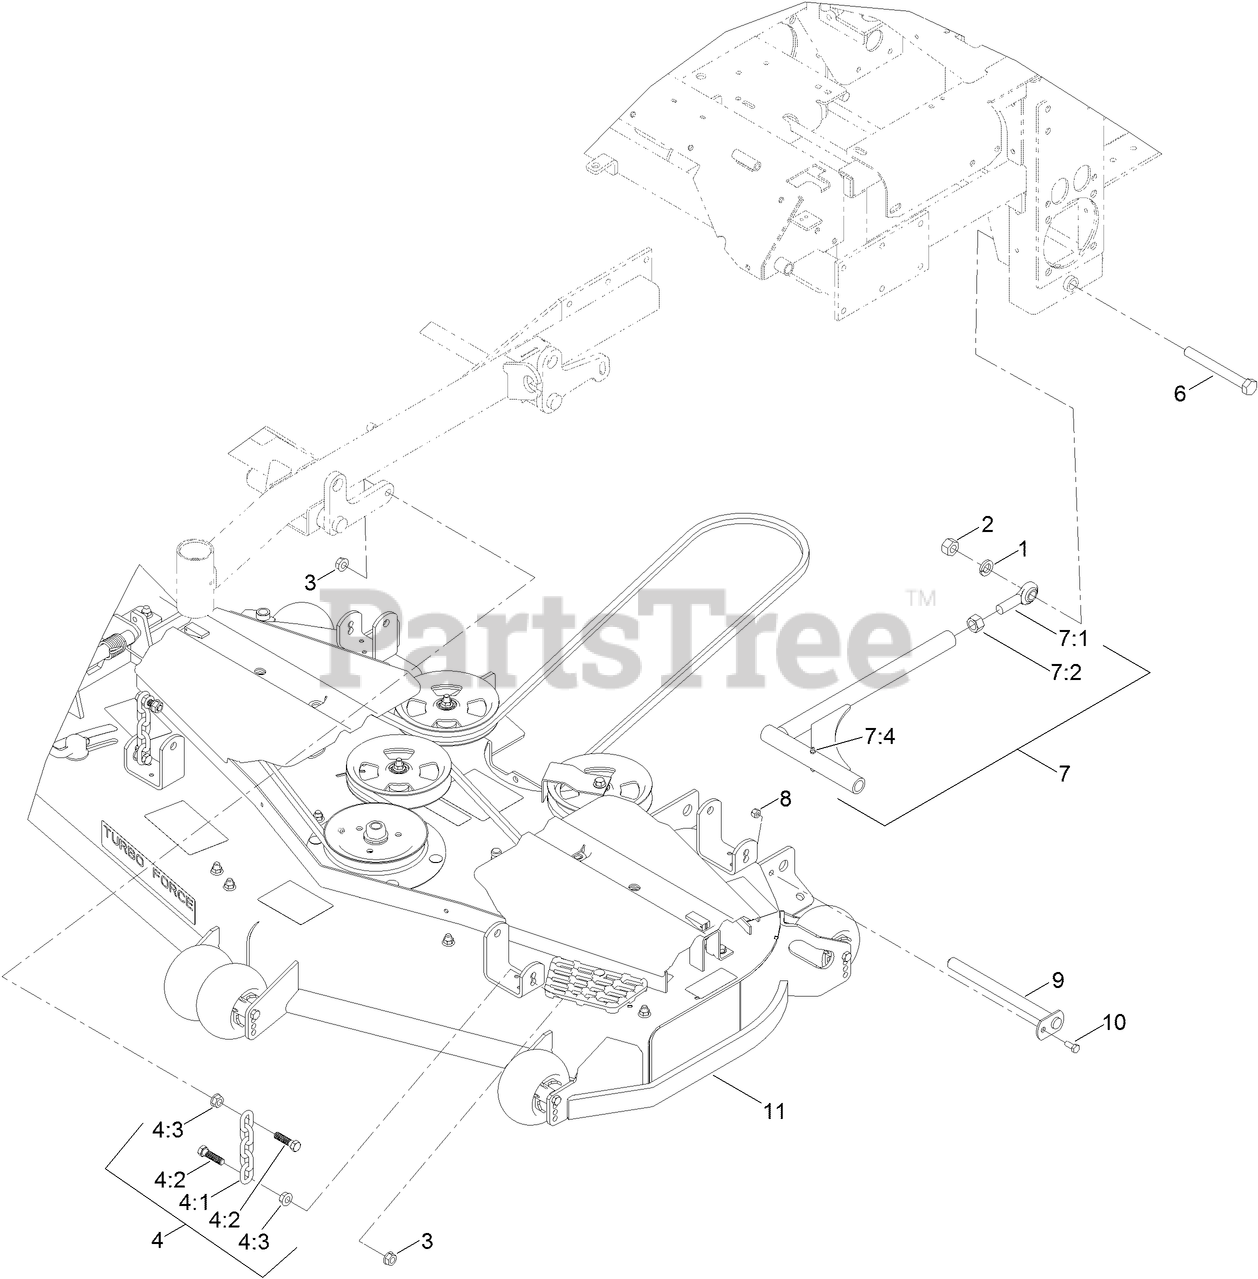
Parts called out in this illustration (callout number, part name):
1	WASHER-LOCK
2	NUT-HEX
3	NUT-HF
4	DECK CHAIN ASM
4:1	CHAIN-LIFT, DECK
4:2	SCREW-HH
4:3	NUT-HF
6	SCREW-HH
7	STRUT ASM
7:1	BALLJOINT-SPHERICAL
7:2	NUT-HEX
8	NUT-LOCK, NI
9	PIN-STRUT
10	SCREW-HH
